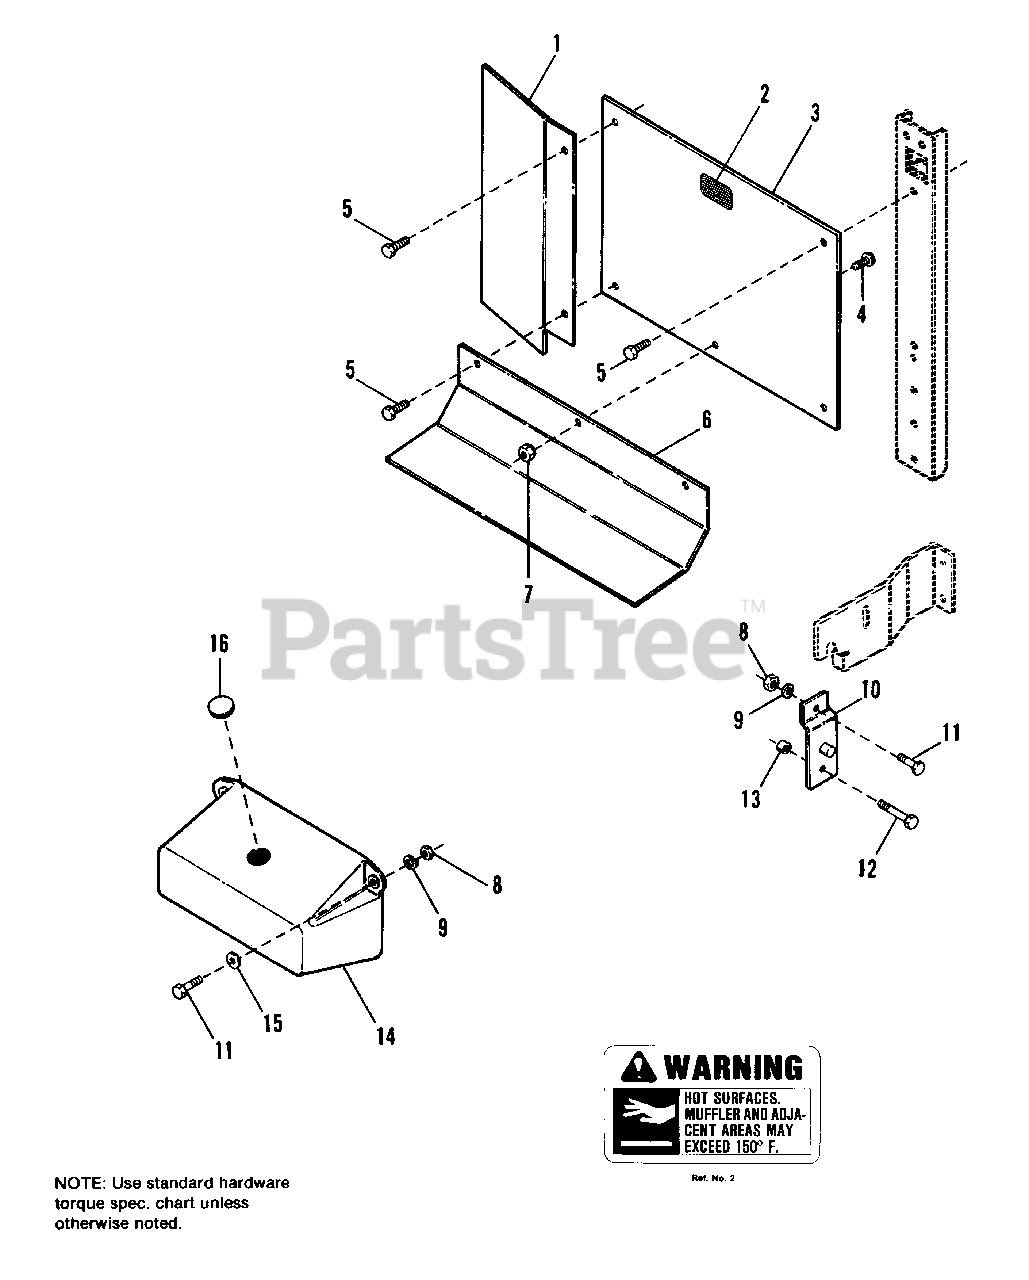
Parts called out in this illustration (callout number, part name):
1	HEAT DEFLECTOR, Side
2	DECAL, Hot Surface
3	HEAT DEFLECTOR, Side
4	SCREW, Truss Heat Head, 10-32
5	SCREW, Taptite, 5/16-18 x 1/2
6	HEAT DEFLECTOR, Lower
7	NUT, Hex Head, 10-32
8	NUT, Hex Head, 5/16-18
9	LOCKWASHER, 5/16
10	SUPPORT ASSEMBLY
11	CAPSCREW, Hex Head, 5/16-18 x 1
12	CAPSCREW, Hex Head, 5/16-18 x 1-1/2
14	COUNTERWEIGHT
15	WASHER
